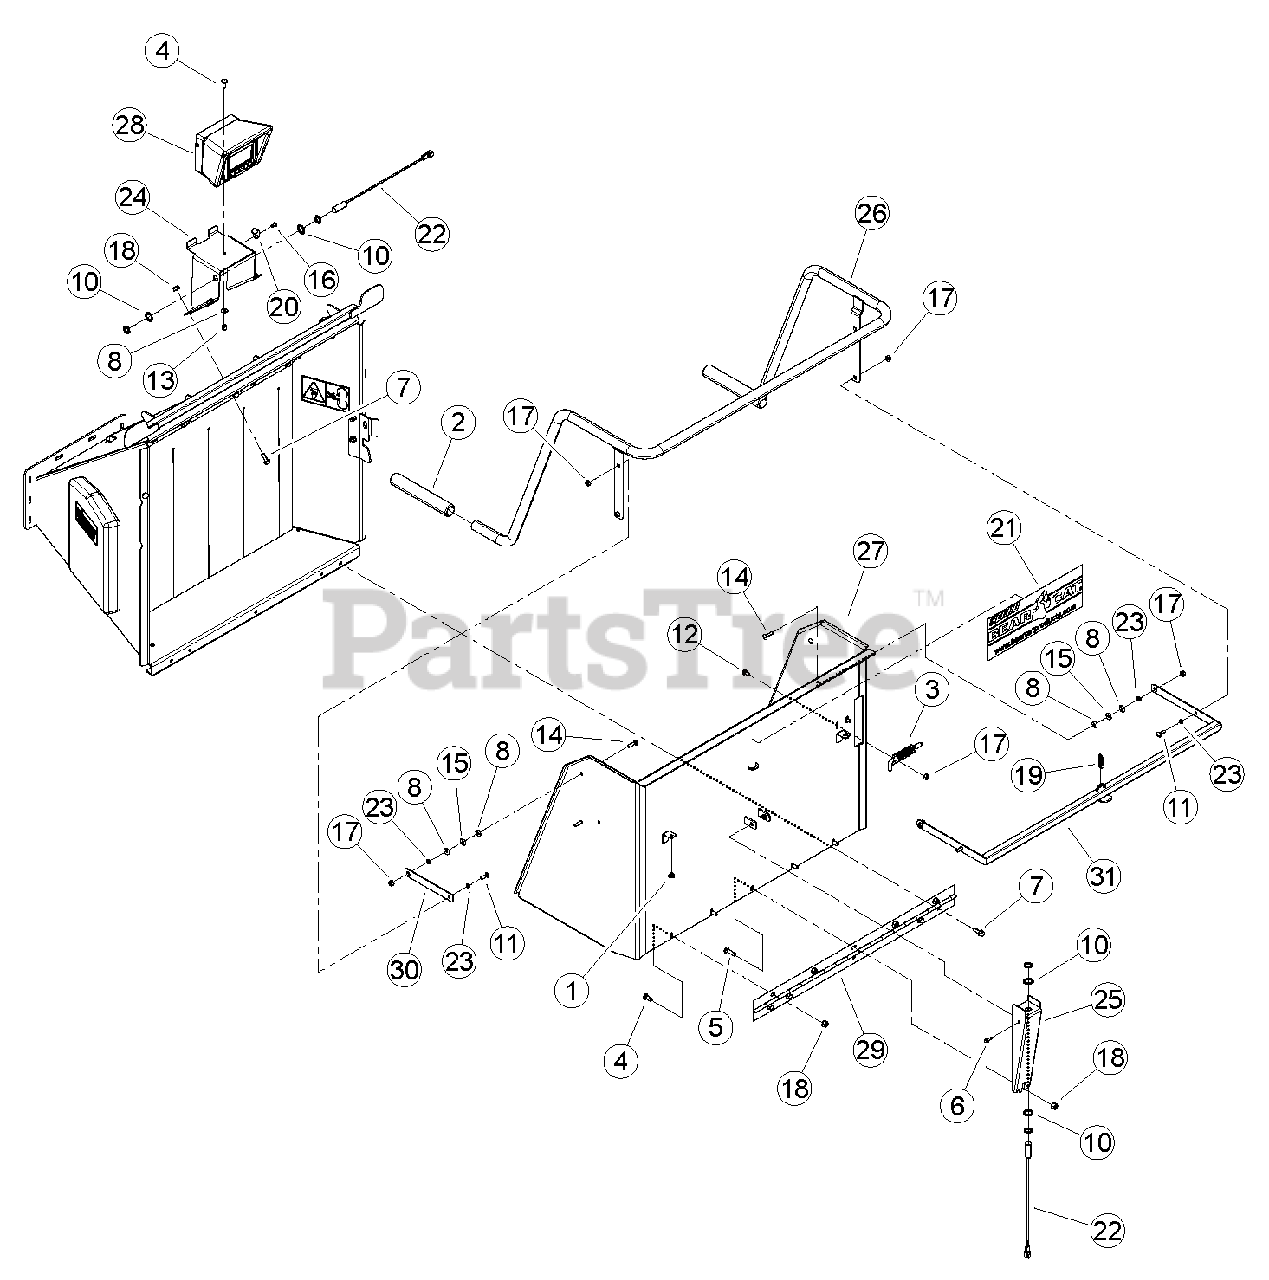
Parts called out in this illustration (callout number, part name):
1	BUMPER, RUBBER
2	GRIP, 1.219 X 10.00
3	LATCH, RH HINGE
4	BOLT, 3/8 X 1" GR5 CRG NC ZP
5	BOLT, 3/8 X 1-1/2" GR5 CRG NC ZP
6	BOLT, 1/4-20 X 3/4 HWH GR5 CZP
7	BOLT, 3/8 X 1 FLANGE NC
8	WASHER, 5/16" FLAT ZP
9	WASHER, 3/8" SAE FLAT ZP
10	WASHER, 3/4 INTERNAL LOCK
11	BOLT, 5/16 X 1" GR5 CRG ZP
12	BOLT, 5/16 X 3/4 GR5 CRG NC ZP
13	NUT, 3/8" NE NYLOCK ZP
14	BOLT, 5/16 X 1-1/4" GR5 CRG ZP
15	WASHER, 5/16" ID 7/8" OD NYLON FLAT
16	RIVET, AL BLIND 1/4 X 3/4 DOME HEAD
17	NUT, 5/16-18 NYLOCK-FLANGE
18	NUT, 3/8-16 NYLOCK FLANGE
19	SPRING, 1/2 X 2.00 LG ZP
20	CLAMP, CABLE MOUNT
21	DECAL, BEARCAT WEB
22	SENSOR, M18 PROXIMITY (REPLACEMENT PART)
23	SPACER, IDLER PIVOT
24	MOUNT, 6" DDC
25	MOUNT, 6" KNEEBAR PROX SENSOR
26	WELDMENT, KNEEBAR 6"
27	WELDMENT, 6" INFEED TRAY
28	ASSEMBLY, DDC ENCLOSURE
29	HINGE, EXTENSION TRAY
30	LINK, PARALLEL
31	WELDMENT, KNEEBAR PIVOT
